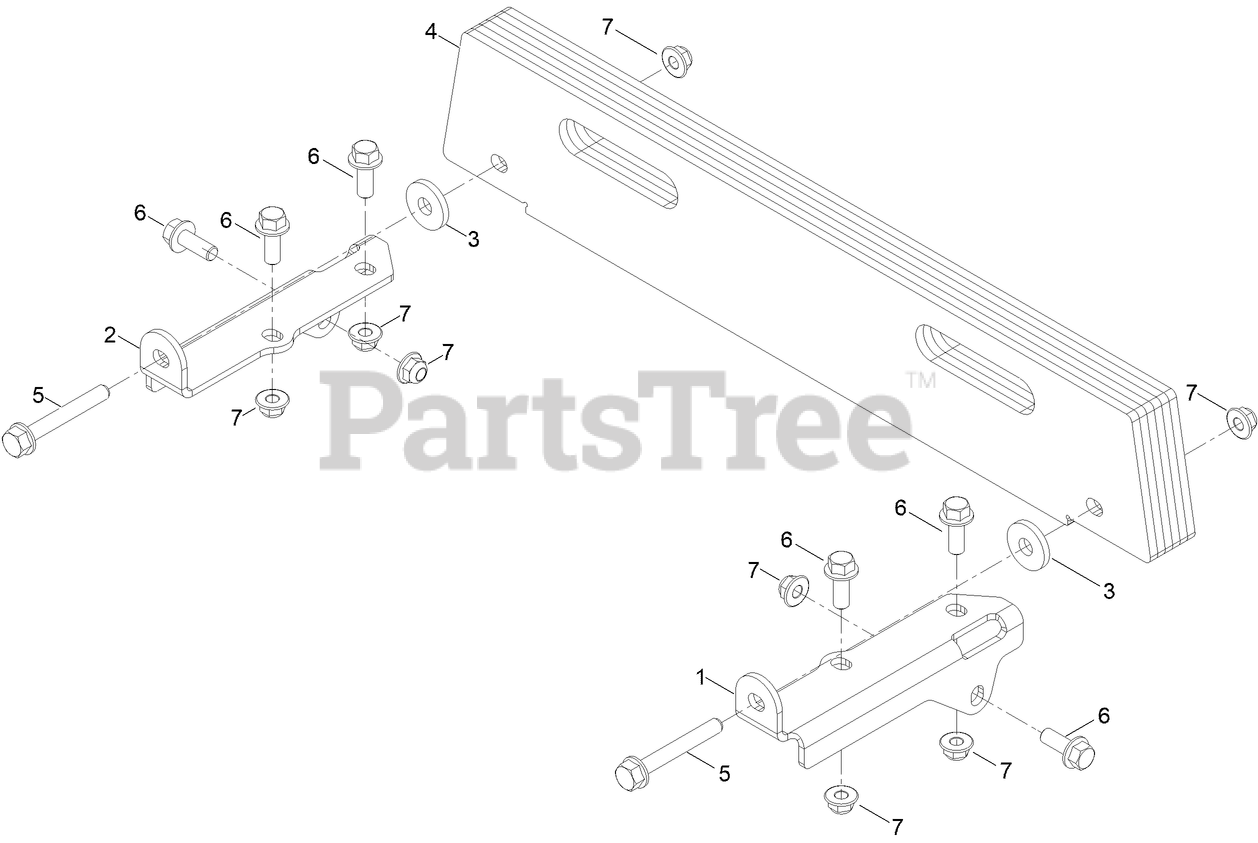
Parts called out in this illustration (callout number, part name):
1	BRACKET-WEIGHT TITAN [BLACK]
2	BRACKET-WEIGHT TITAN [BLACK]
3	WASHER
4	WEIGHT-BAGGER
5	SCREW-SPCL
6	SCREW-HHF
7	NUT-HF, NI
